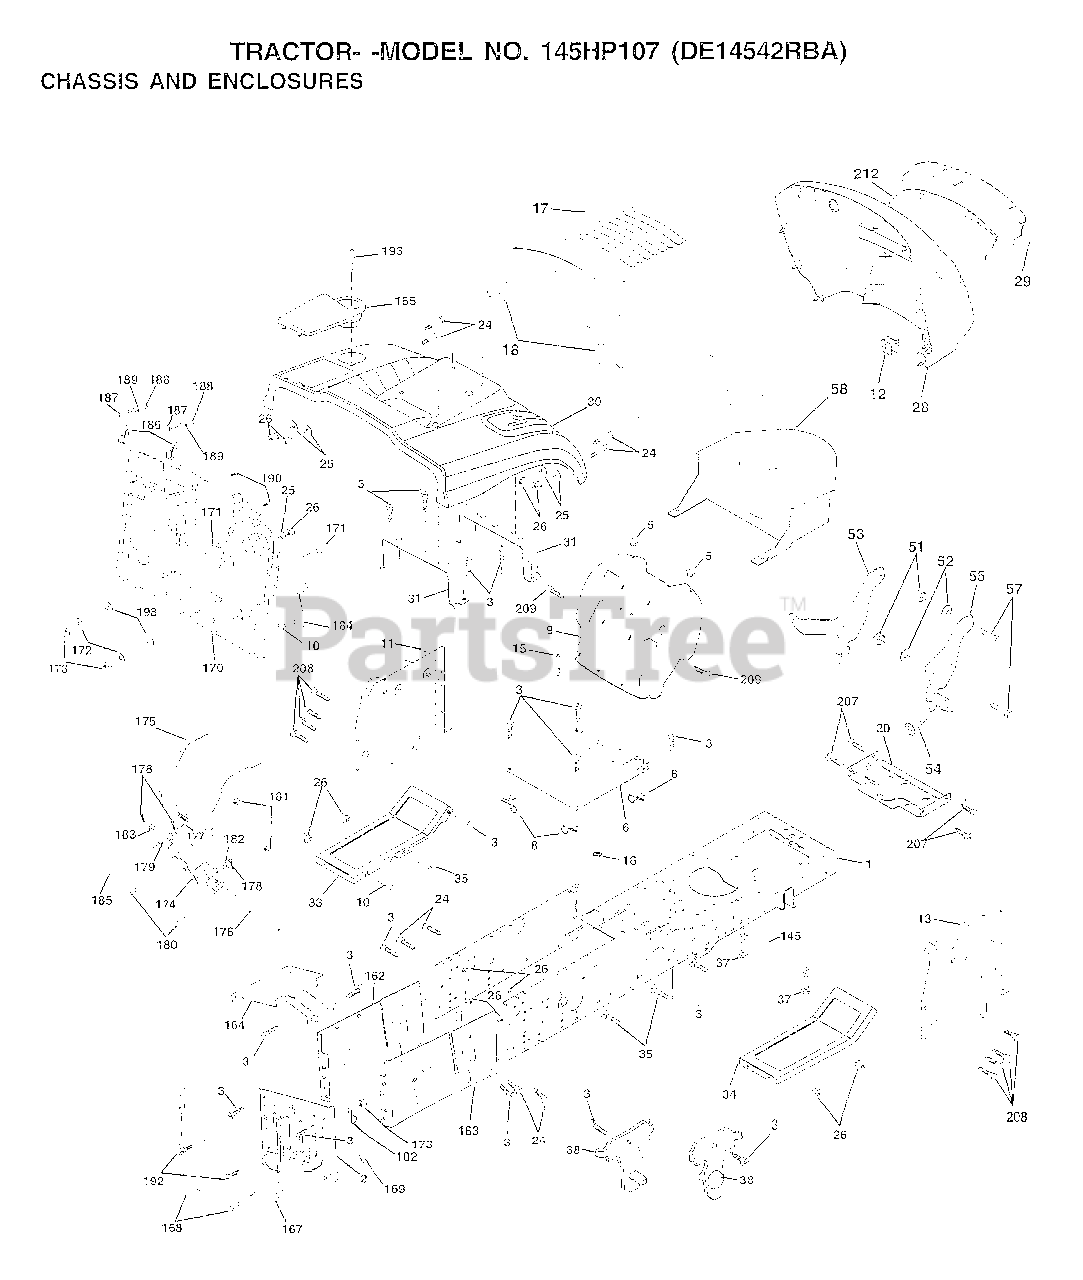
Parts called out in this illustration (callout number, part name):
2	DRAWBAR.CRD
3	SCREW
5	BUMPER-HOOD/DASH
6	SADDLE
8	"CLIP,INSULATOR"
9	DASH
11	"PANEL-DASH,LH"
12	CLIP.TINNERMAN
15	SCREW
20	"PLATE-MTG,BATT/FU"
24	BOLT
25	WASHER
26	NUT
30	FENDER.CRD.SAGE
31	BRKT.SUPT.FENDER.CRD
33	FOOTREST
34	FOOTREST.PNT.RH
35	BOLT
37	SCREW LT
38	BRKT ASM PIVOT MOWER REAR
51	NUT
52	WASHER
53	BRACKET.GRILLE.LH
54	SCREW.HEX.WS.HD
55	BRACKET.GRILLE.RH
58	AIR DUCT
102	CLIP T
145	"ROD POVOT,CHASSIS"
162	BRKT.EXT.CHASSIS.LH.CRD
163	BRKT.EXT.CHASSIS.RH.CRD
164	SUPPORT.BATTERY.CRD
165	COVER.BATTERY.CRD.BLACK.LT
167	SUPT.ASM.BACKPLATE
168	BOLT-RD HD SQ NK
170	COVER.BACKPLATE.BLACK
171	BOLT.HEX.3/8-16X2-1/2
173	NUT
174	BRKT.SWITCH.FBI.CRD
175	GRUARD.DOOR.REAR.CRD
176	HINGE PIN
177	SPRING.COVER.LH
179	ROD.PIVOT.FBI.CRD
182	WASHER.385X.625
183	WASHER
184	BRKT.ACTUATOR.BAG.CRD
185	TUBE.LEVER.SWCH.FBI.CRD
186	LATCH ASSY.BAGGER
187	WELDNUT
188	WASHER #10
189	LOCKWASHER
190	SCREW
192	SCREW LT
193	SCREW
198	NUT PUSH
207	SCREW
208	SCREW
209	SCREW
212	INSERT LENS REFLECT
